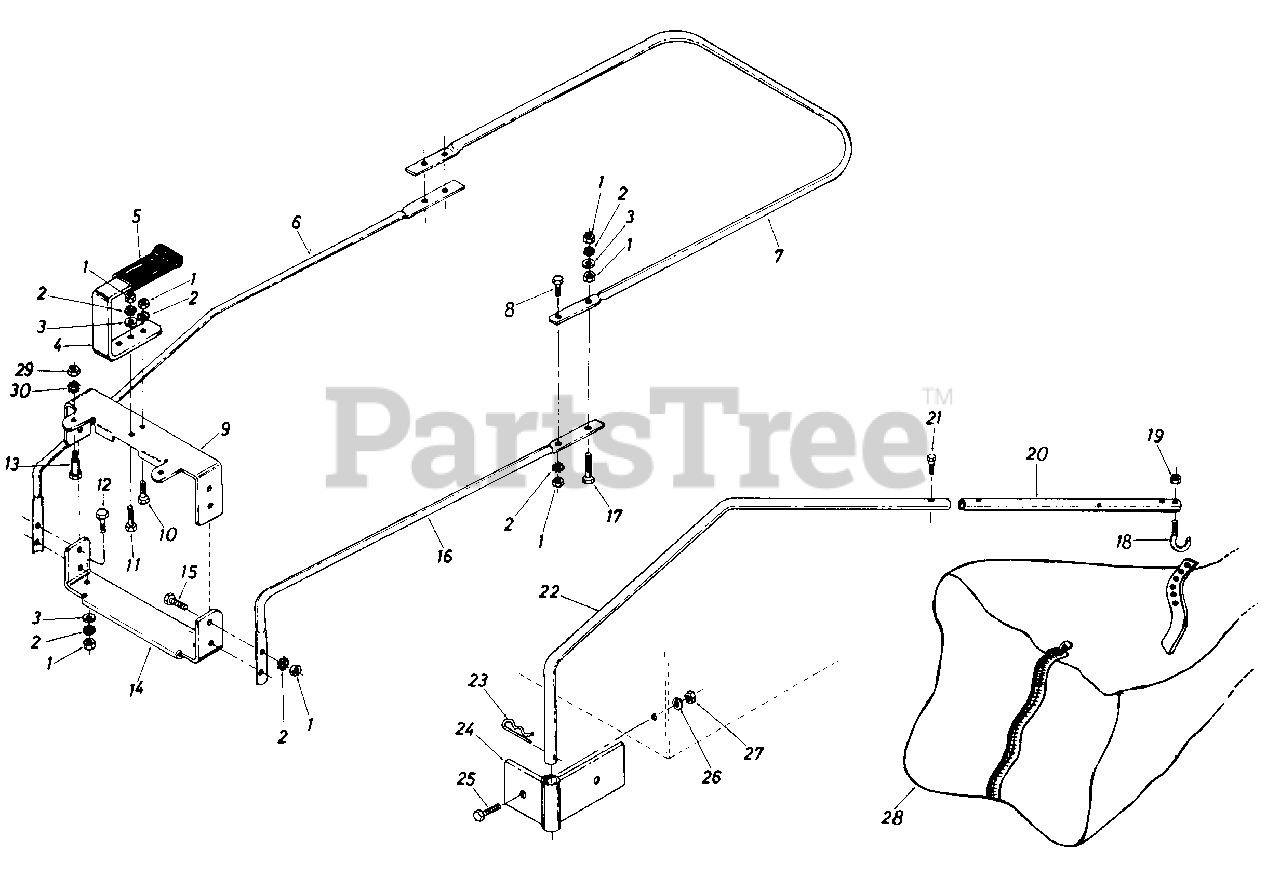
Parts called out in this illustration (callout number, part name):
1	Hex Nut 1/4-20 Thd.*
2	Ext. L.-Wash. 1/4" Scr.*
3	Fl.-Wash. .281 I.D. x .50" O.D.
6	Lower Frame Arm
7	Upper Frame Half
8	Hex Scr. 1/4-20 x 1.00" Lg.*
9	Upper Opening Support
10	Hex Scr. 1/4-20 x .62" Lg.*
11	Hex Scr. 1/4-20 x .75" Lg.*
12	Hex Scr. 1/4-20 x .50" Lg.*
13	Shld. Scr. .437" Dia. x .350
14	Lower Opening Support
15	Hex Scr. 1/4-20 x 1.00" Lg.*
16	Lower Frame Tubing
17	Hex Scr. 1/4-20 x 1.50" Lg.*
19	Hex Ins. L.-Nut 1/4-20 Thd.
22	Lower Holding Arm
23	Internal Cotter Pin 5/8" Dia.
24	Hitch Bracket
25	Hex Sems Scr. 5/16-18 x .75" Lg.*
26	L.-Wash. 5/16" Scr.*
27	Hex Nut 5/16-18 Thd.*
28	Grass Catcher Bag
29	Hex Nut 5/16-18 Thd.*
30	Ext. L.-Wash. 5/16" Scr.*
